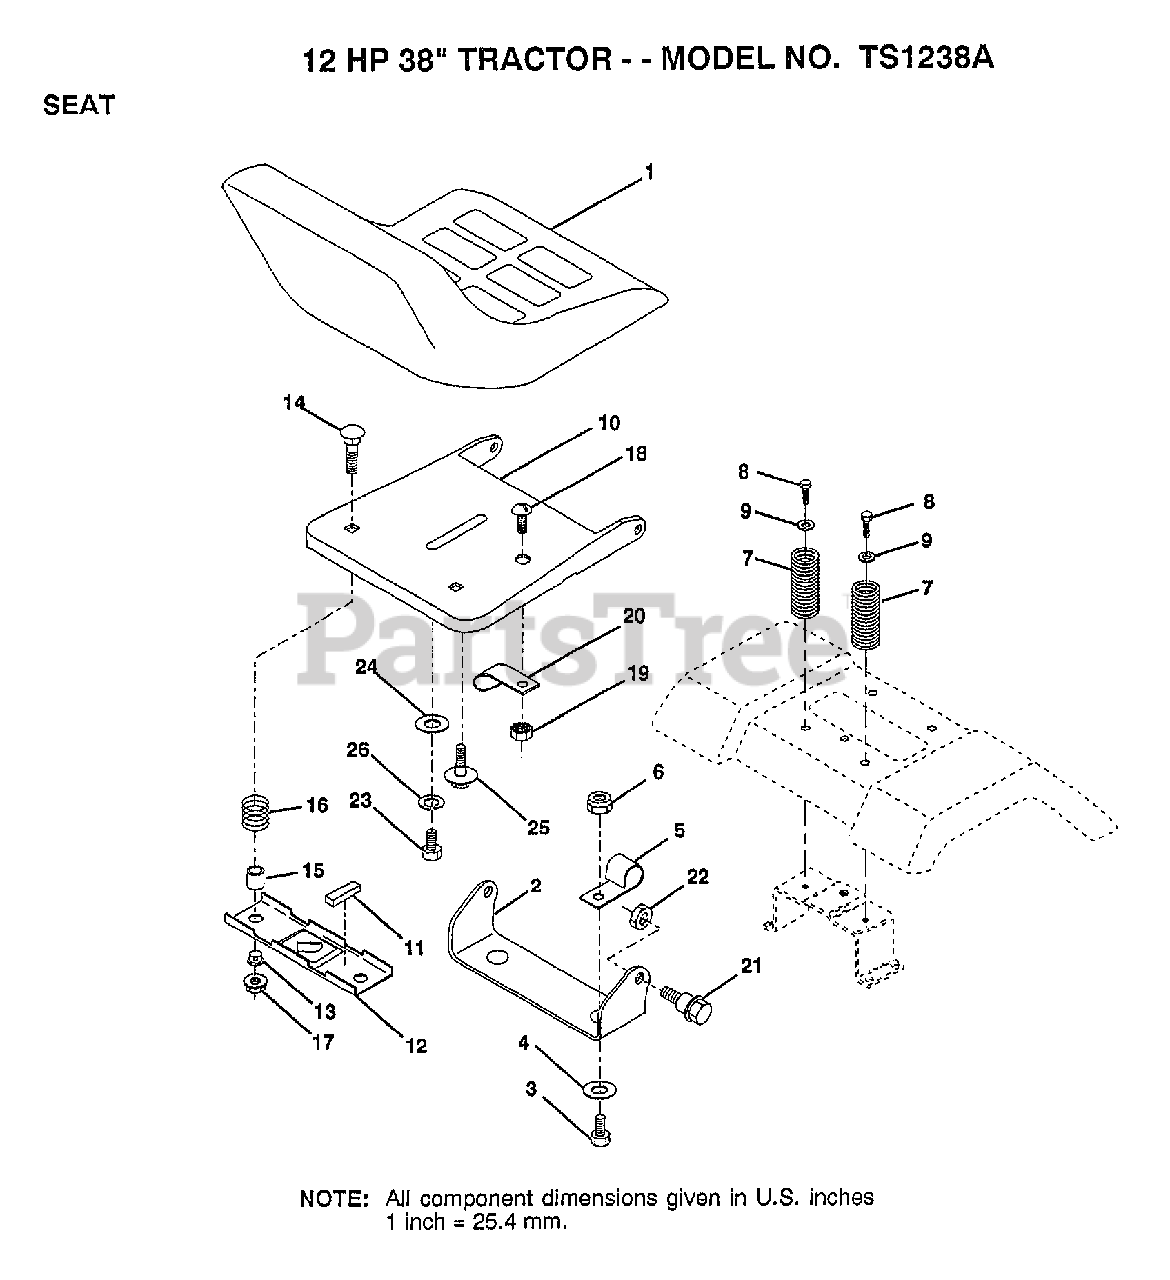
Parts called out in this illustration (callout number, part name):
4	WASHER PM
5	CLIP T
7	SPRING COMPRESSIO
8	SCREW GTV
9	WASHER
11	STRIP FORM
12	BRKT SWITCH
13	BUSHING
15	SPLIT SPACER
16	SPRING
19	"NUT,KEPS"
21	BOLT.SHLD.5/16-18
23	BOLT
24	WASHER
25	"BOLT,SHOULDER"
26	LOCKWASHER
